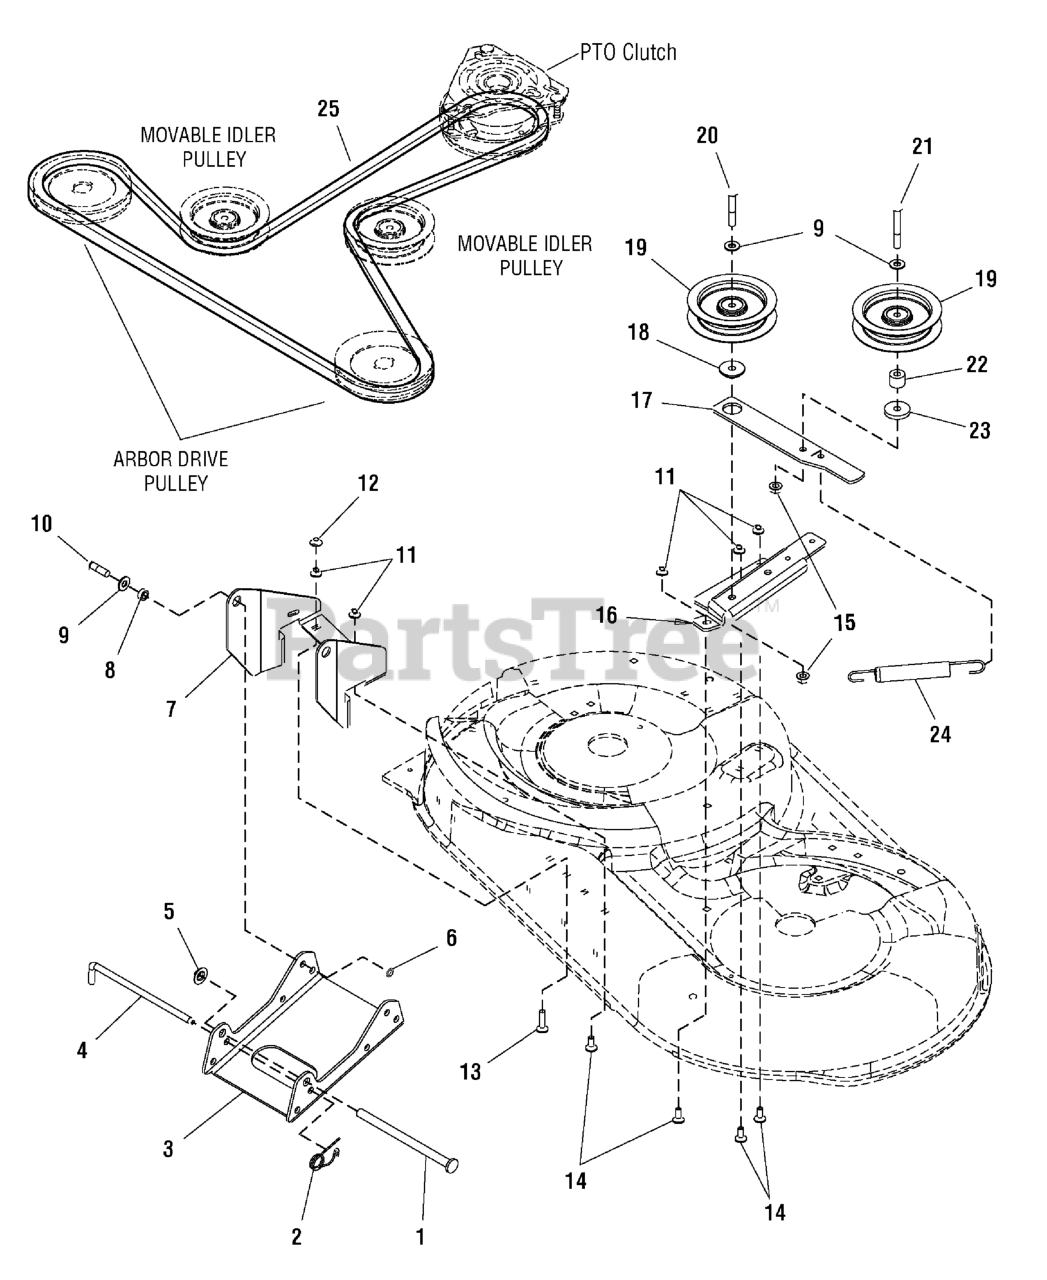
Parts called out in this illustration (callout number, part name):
1	ROD, 7-5/8 Long
2	RETAINER, Pin Spring
3	HITCH, Mower
4	ROD, ZTR
5	NUT, Push 1/2 Stud Capped
6	NUT, Hex Lock ESNA Light, 3/8-16 NC3B
7	HITCH, Mower Front 42"
9	WASHER, 3/8
10	CAPSCREW, Hex Head 3/8-16 x 1-1/4, G8
11	NUT, Hex Whiz Lock Flange, 5/16-18
12	NUT, Hex Flange Two-Way Lock, 5/16-18
13	BOLT, Carriage, 5/16-18 x 1 1/4
14	CARRIAGE BOLT, 5/16-18 x 3/4, G5
15	NUT, Hex Flange Whiz Lock, 3/8-16
16	BRACKET, Idler Fixed
17	ARM, Idler Clutch
18	SPACER, Powdered Metal
19	PULLEY, Idler 4"
20	CAPSCREW, Hex Head 3/8-16 x 2-1/4, G5
21	CAPSCREW, Hex Head, 3/8-16 x 2-3/4, G5
23	WASHER, 3/8 Black
24	Spring, Extension 7-7/8 Long
25	BELT, HA 98
